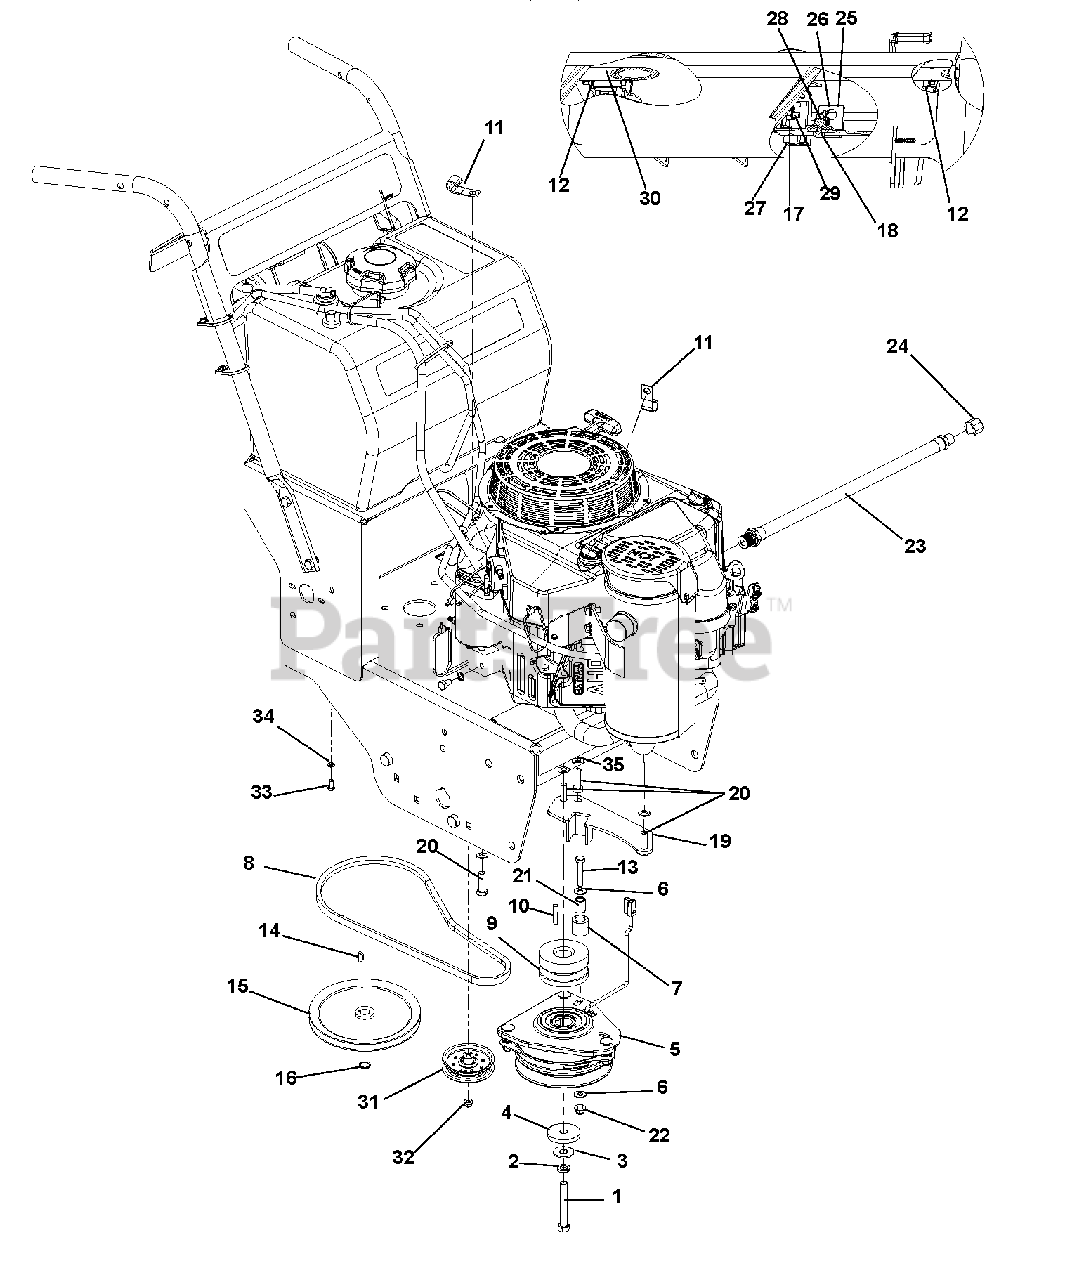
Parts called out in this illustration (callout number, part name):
1	Bolt, .44-20 x 3.00 Hex Grade 5
2	Washer, Lock .44 x .109
3	Washer, Flat-Steel .50 x 1.25 x .083
4	Washer, Flat-Steel .469 x 2.00 x .25
5	Clutch Assembly, Ogura
6	Washer, Flat-Steel .531 x 1.062 x .095
7	Bumper, Rubber .62 x 1.0 x .88
8	Belt, HA 40.60 Raw Laminated
9	Sheave,1.002 ID x 3.222 PIN
10	Key, Square .248 x 1.25 x .248
11	P-Clip, .500 Insulated
12	Screw, Tap 10-24 x .50 HWH
13	Bolt, Hex .31-18 x 1.75 Grade 5
14	Key, Woodruff .19 x .75 HRD #9
15	Pulley, V 7.50 x .626
16	Ring, Retaining-External .579 x .035
17	Nut, Locking Nylon 10-24 w/Insert (SN 000101 – 019999)
18	Bolt, .25-20 x .750 Hex Grade 5
19	Weldment, Clutch Stop
20	Bolt, Hex .38-16 x 1.25 FTH Grade 5 EP80YZ (SN 000101 – 020999)
22	Nut, Nyloc Flange, .31-18
23	Drain, M20 Oil
24	Pipe Cap 3/8 NPT Female
25	Bracket, Brake Link
26	Spring, Tension .047 x .438 x 1.45
27	Switch, Interlock
28	Nut, .25-20 Nyloc Flange
29	Screw, Machine 10-24 x .75 Hex Washer Head
30	Weldment, Pivot Tube
31	Assembly, Idler 4"
32	Nut, Locking NylonFlange .38-16
33	Bolt, Hex .31-18 x .75 Grade 5
34	Washer, Lock .31 x .078 Reg
35	Washer, 3/8" Spring Disc
